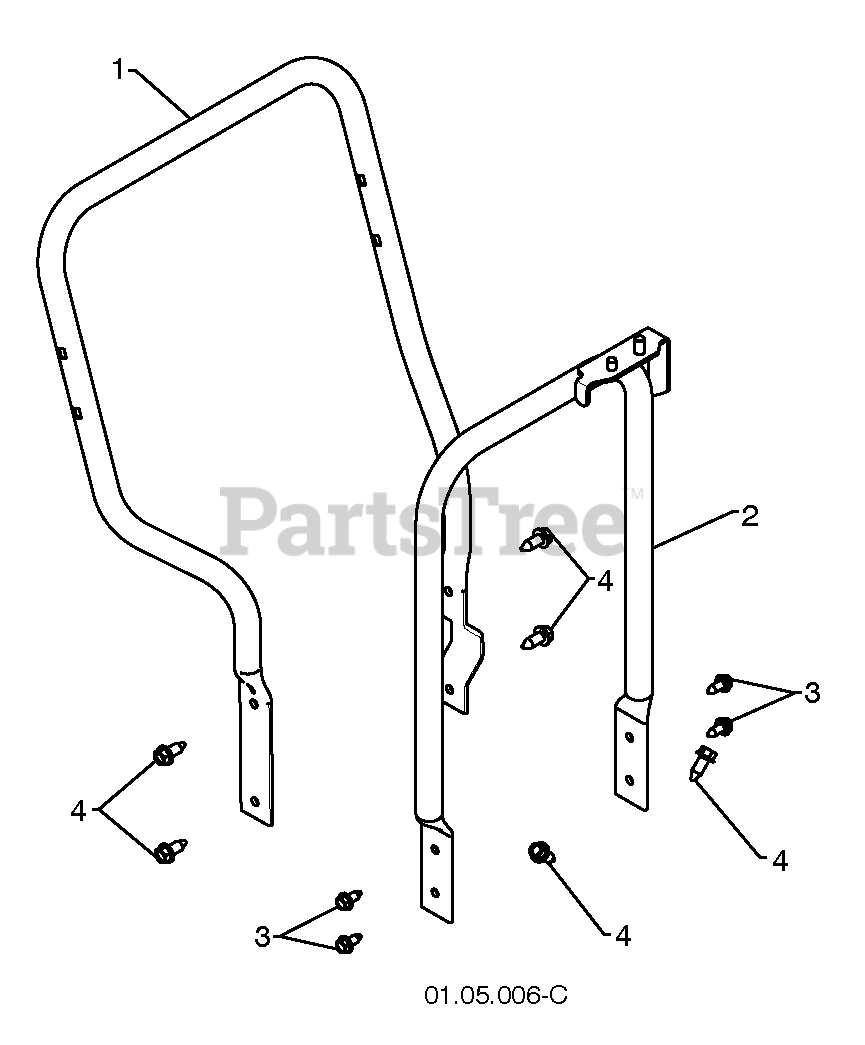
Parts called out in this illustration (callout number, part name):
1	LOWER TUBE GRAY
2	PIVOT SUPPORT
3	BOLT 5/16-18 X .750
4	SCREW 3/8-16 X 1.00
